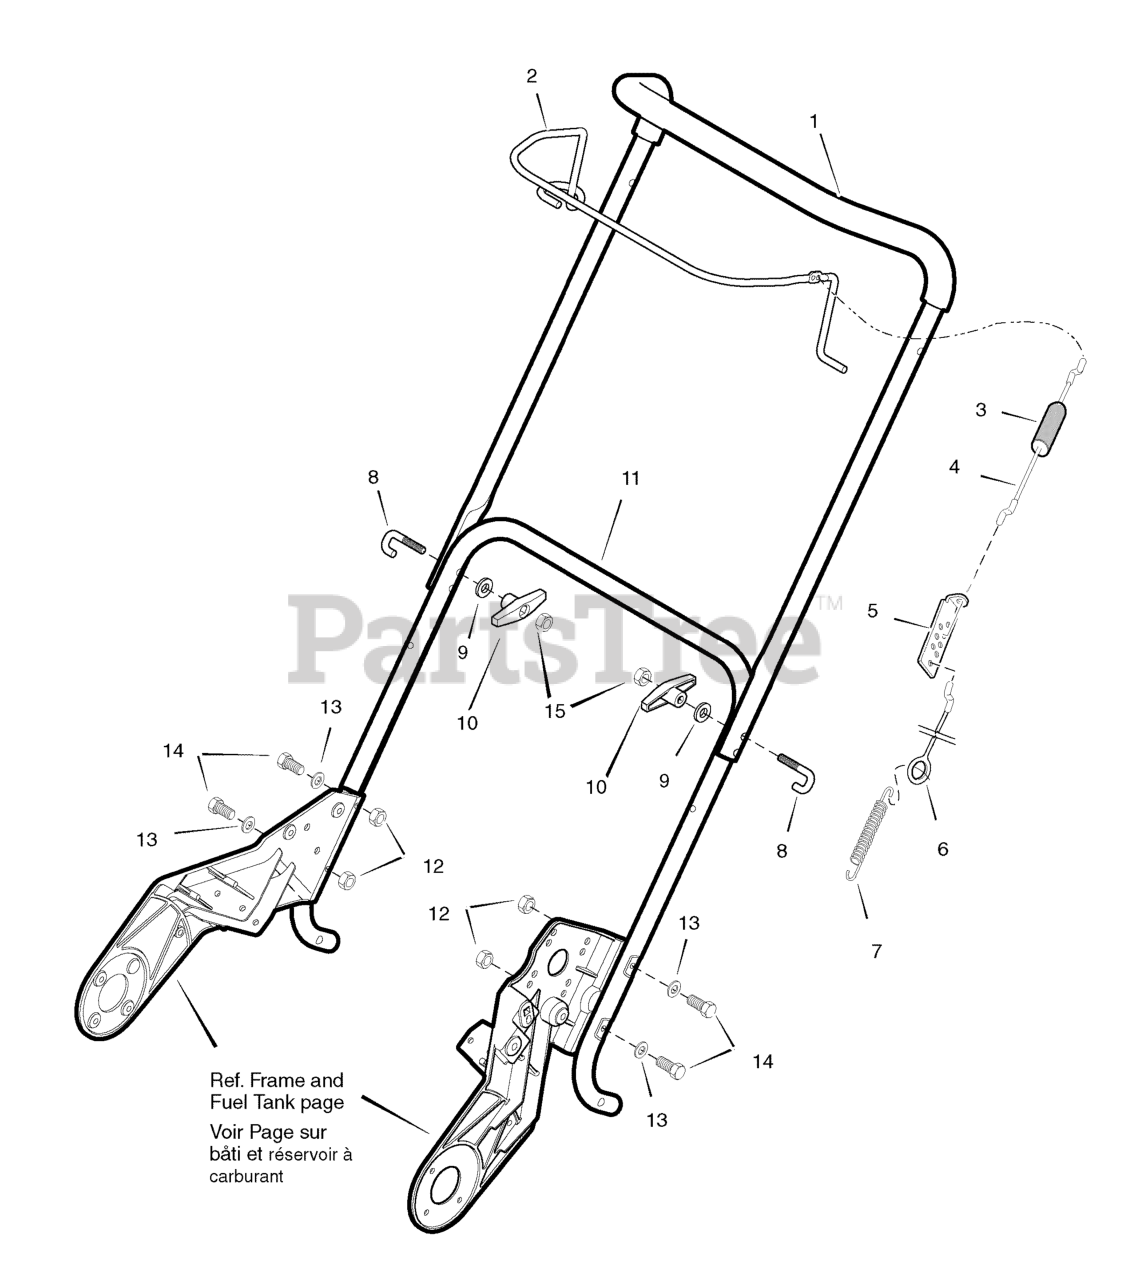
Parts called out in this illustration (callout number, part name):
1	Handle & Grip Assembly
2	Control, Bail
3	Boot, Clutch Spring
4	Cable, Upper Control
5	Bracket, Control Adjust
6	Cable, Lower Control
10	Knob, Wing
11	Handle, Lower
12	Nut
13	Washer
14	Screw, 1/4-20 x1.25
15	Nut, 5/16-18
